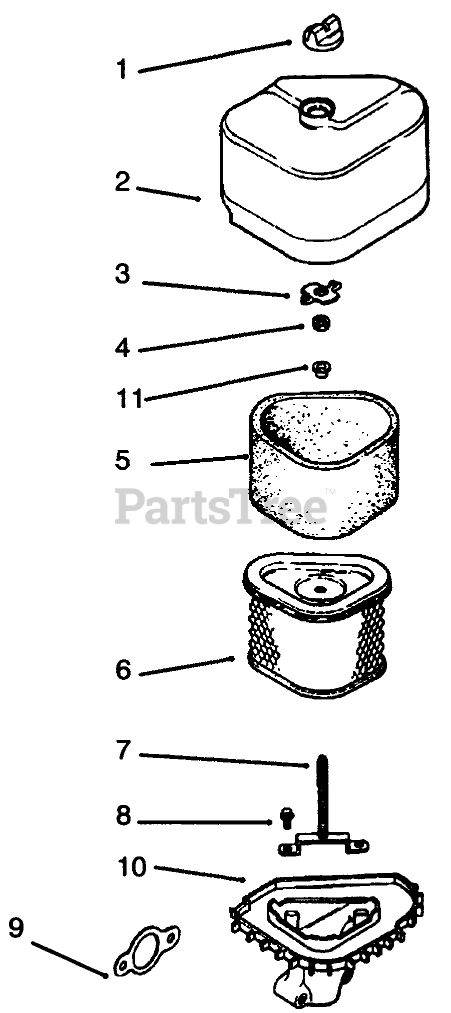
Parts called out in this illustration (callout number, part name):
1	Knob-Air Cleaner Cover
2	Cover-Air Cleaner
3	Nut-Wing
4	Washer
5	Element-Air Cleaner
6	Element-Precleaner
7	Stud-Mounting Plate
8	Screw-Mounting Plate
9	Gasket
10	Base-Air Cleaner Incl 7
11	Grommet
